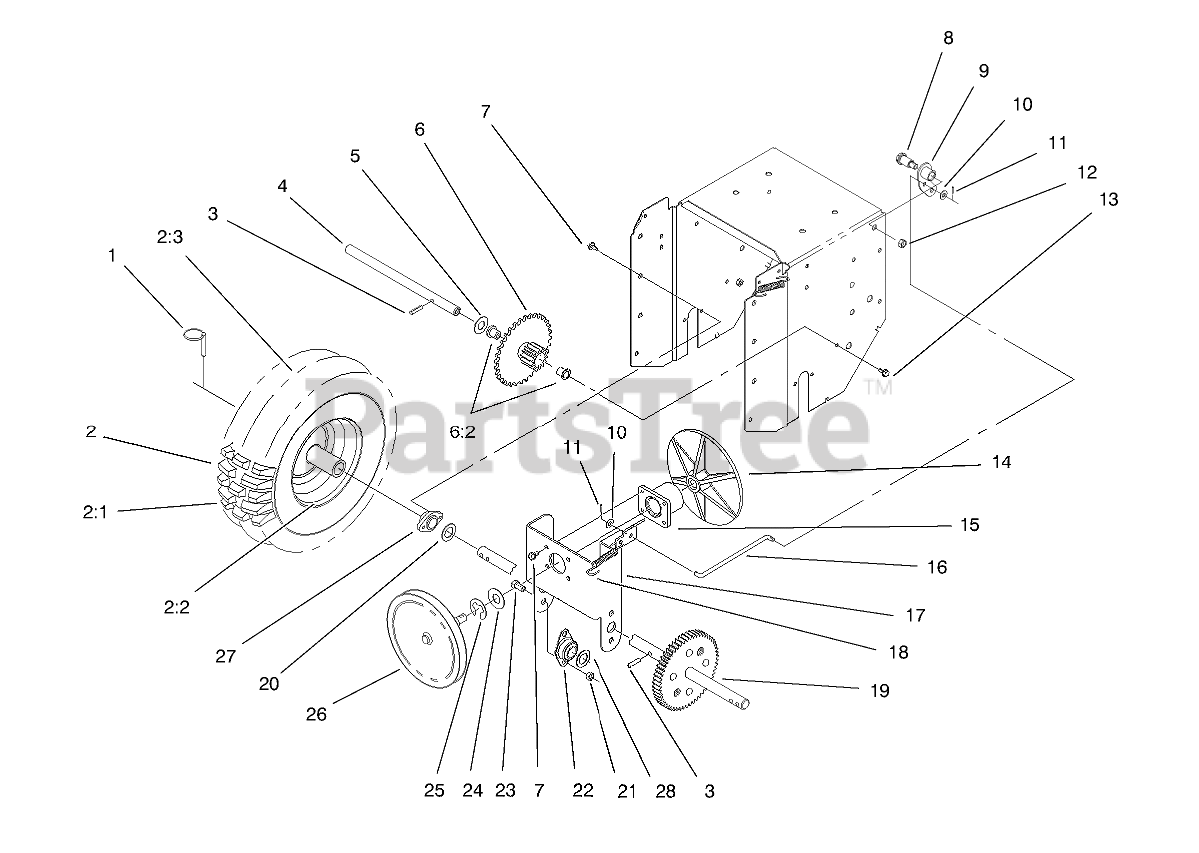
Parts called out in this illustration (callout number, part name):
1	PIN-LYNCH
2	ASM-Wheel
2:2	RIM-WHEEL
2:3	TUBE-INNER
3	PIN-ROLL, SLOTTED
4	SHAFT-INTERMEDIATE
5	WASHER
6	GEAR/BUSHING ASM
6:2	Bushing (Only On: 38083)
7	SCREW-HWH
8	BOLT-SHOULDER
9	HUB-PIVOT
10	WASHER-FLAT
11	PIN-COTTER
12	NUT-LOCK, NI
13	SCREW-HWHTF
14	DISC-FRICTION
15	BEARING HUB ASM
16	ROD-ENGAGE
17	Frame-Friction Plate
18	SPRING-ENGAGE
20	WASHER-THRUST
21	NUT-LOCK, NI
22	BUSHING
23	SCREW-HH
24	WASHER-THRUST
25	RING-RETAINING, EXT
26	PULLEY/SHAFT ASM
27	BEARING-AXLE
28	WASHER-THRUST
